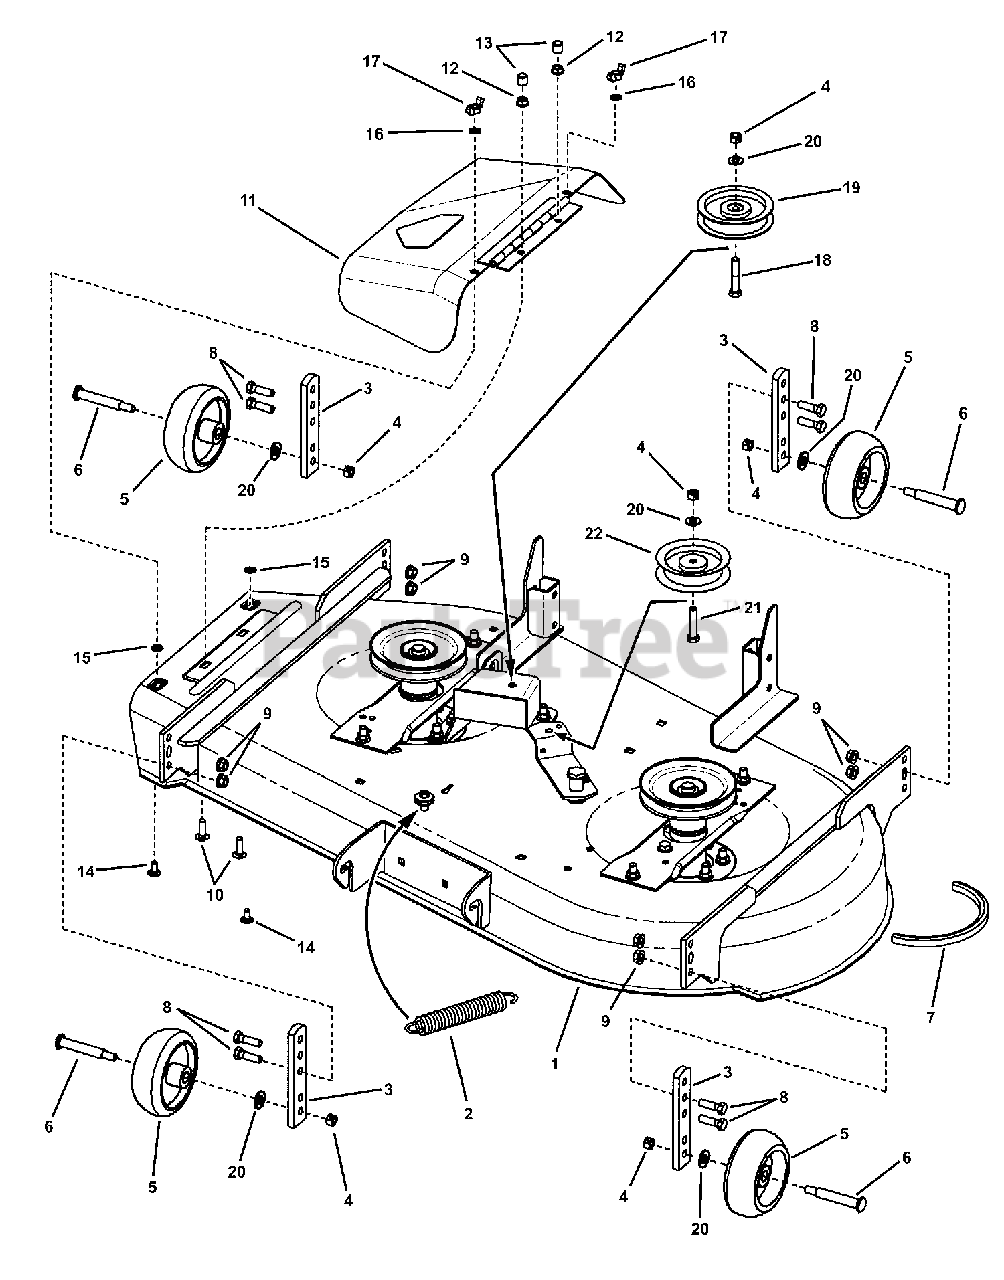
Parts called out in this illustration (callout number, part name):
1	SUB-ASSY, 42" Deck w/Spindles
2	SPRING, Extension, 1.03 Dia. x 6.8 Long
3	POST, Anti-Scalp
4	NUT, 3/8-16 Hex Center Lock, GR 5 or B, YZ
5	WHEEL, GAGE 3.92 X 1.87
6	BOLT, SHOULDER (3/8-16 thread)
7	42" BELT, A Section, 119.25 Effective Length
8	SCREW, 3/8-16 x 1-1/4" Hex Head Cap, GR 5 YZ
9	NUT, 3/8-16 Hex Flange Lock
10	BOLT, 5/16-18 x 1" Short Square Neck Carriage, GR 5
11	ASSEMBLY, 42" Chute & Decal
12	NUT, 5/16-18 Hex Flange Lock, GR 5
13	VINYL CAP
14	BOLT, 5/16-18 x 5/8" Short Square Neck Carriage, GR 5
15	BOLT RETAINER, 5/16" Black
16	WASHER, 5/16" Split Lock
17	WING LOCKNUT, 5/16-18- YZ
18	SCREW, 3/8-16 x 2" Hex Head Cap, GR 5 YZ
19	PULLEY, Flat Idler 4-1/8" Dia.
20	WASHER, 3/8" Flat SAE
21	SCREW, 3/8-16 x 1-3/4" Hex Head Cap, GR 5 YZ
22	PULLEY, Flat Idler (4.00 O.D.)
